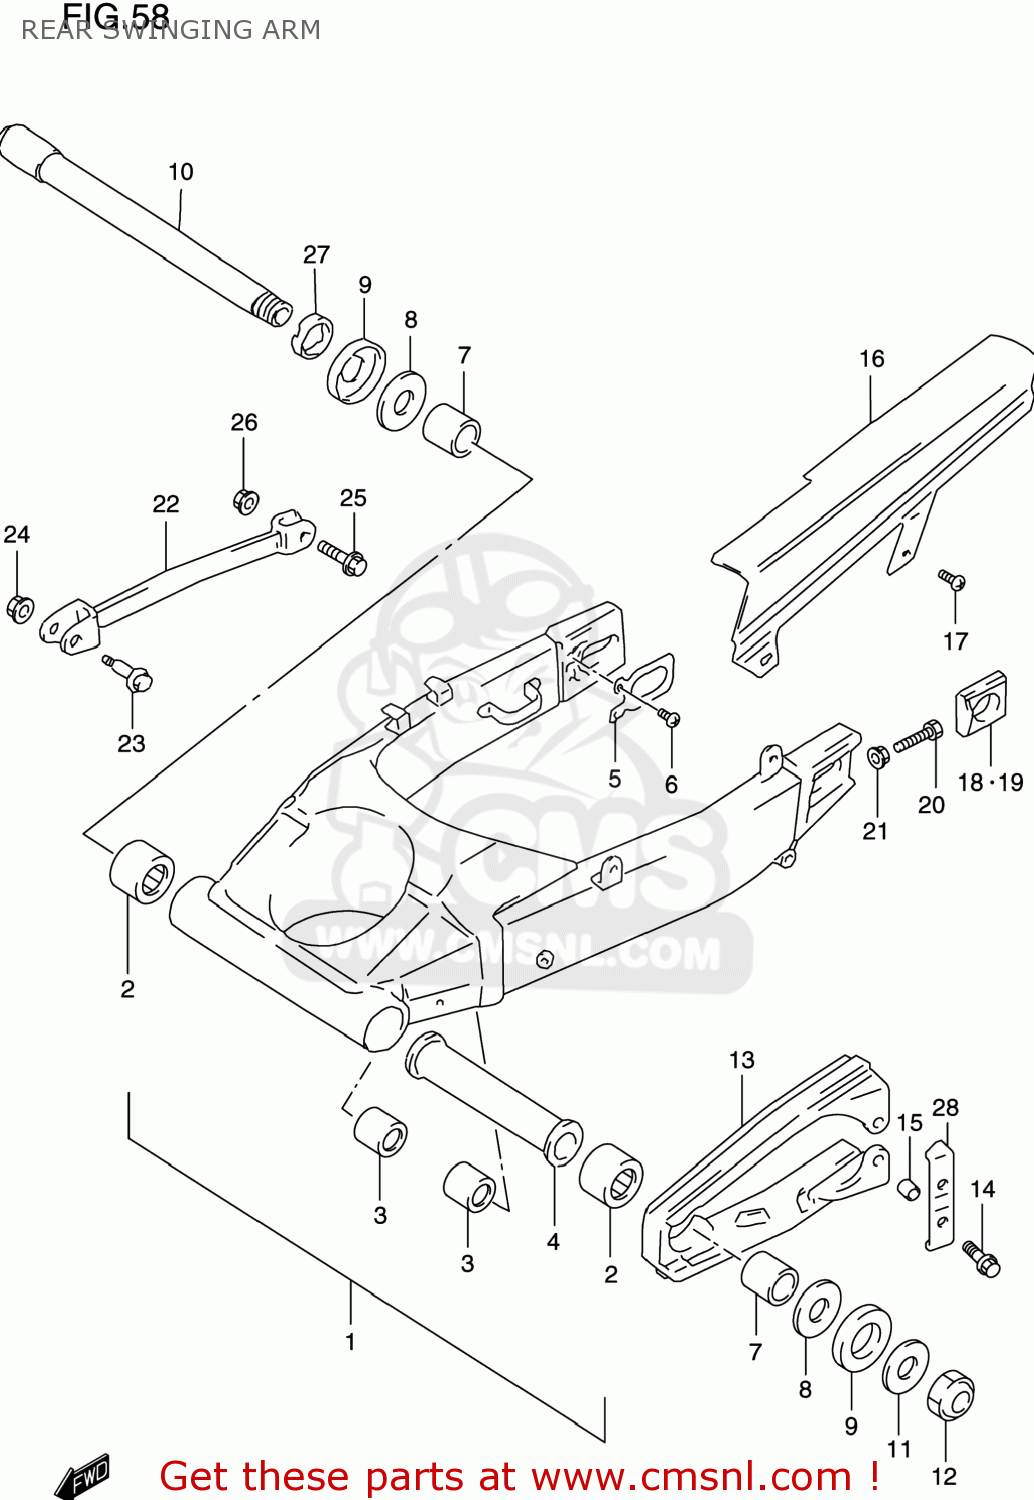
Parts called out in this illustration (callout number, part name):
1	SWINGINGARM ASSY,RR
2	BEARING(30X40X25)
3	BEARING(17X24X20)
4	SPACER,REAR SWING PIVOT,CENTER
5	PLATE,RR SWING ARM BRKT
6	SCREW
7	SPACER,REAR SWING ARM PIVOT
8	WASHER
9	DUST SEAL,RR SWGARM PIVOT
10	SHAFT,RR SWINGINGARM PIVOT
11	WASHER(25.2X42X3.2)
12	NUT
13	BUFFER,CHAIN TOUCH DEFENSE
14	BOLT(6X20)
15	SPACER(6.5X9X5)
16	CASE,CHAIN
17	SCREW(6X16)
18	ADJUSTER,CHAIN,R
19	ADJUSTER,CHAIN,L
20	BOLT(8X50)
21	NUT
22	TORQUELINK,RR
23	BOLT(8X44)
24	NUT
25	BOLT(10X37)
26	NUT
27	NUT,RR SWGARM PIVOT BOLT
28	PLATE,CHAIN BUFFER
